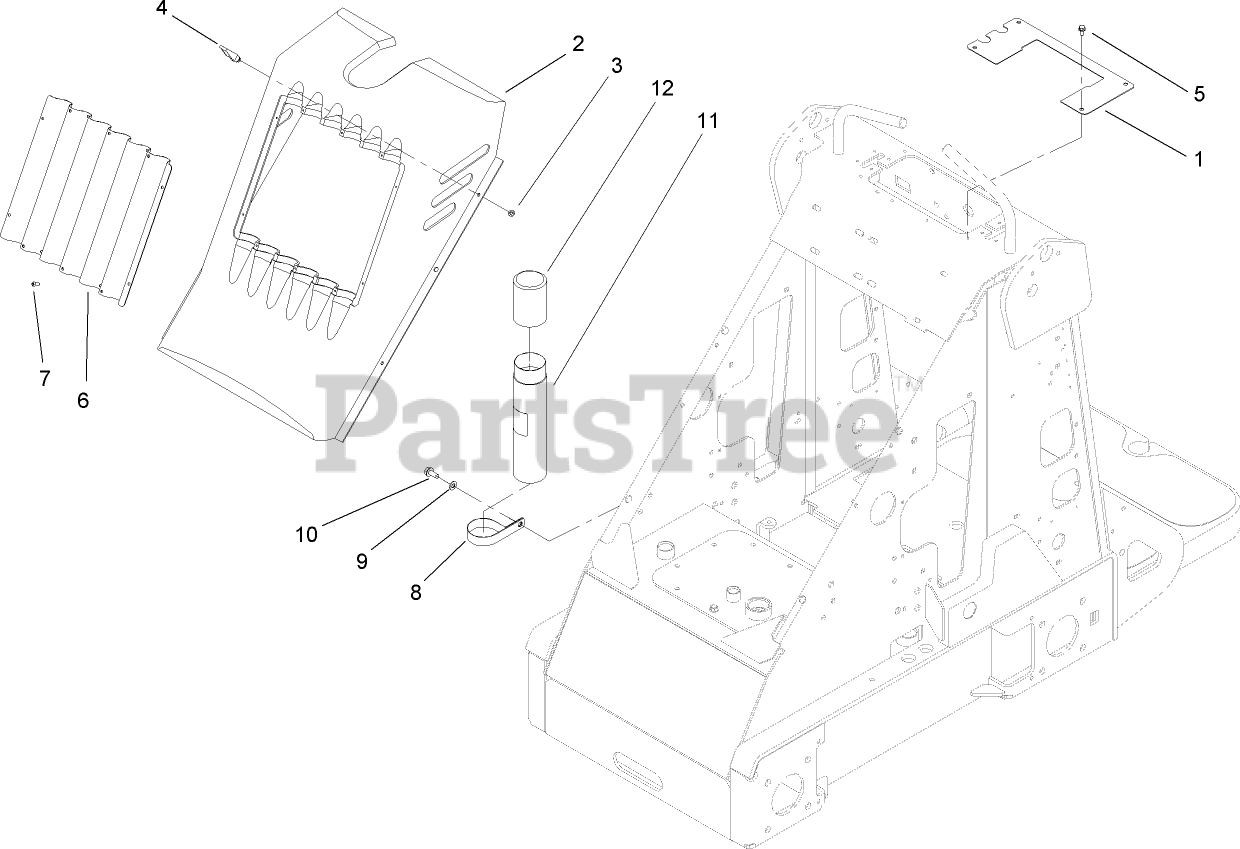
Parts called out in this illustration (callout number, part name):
1	PLATE-COVER
2	COVER-HOOD
3	WASHER
4	LATCH-SWELL
5	SCREW-HWH
6	GRILLE-SCREEN
7	SCREW-PPH
8	CLAMP-R
9	WASHER-PLAIN
10	SCREW-HWHTF
11	TUBE-MANUAL
12	CAP-HOUSING
